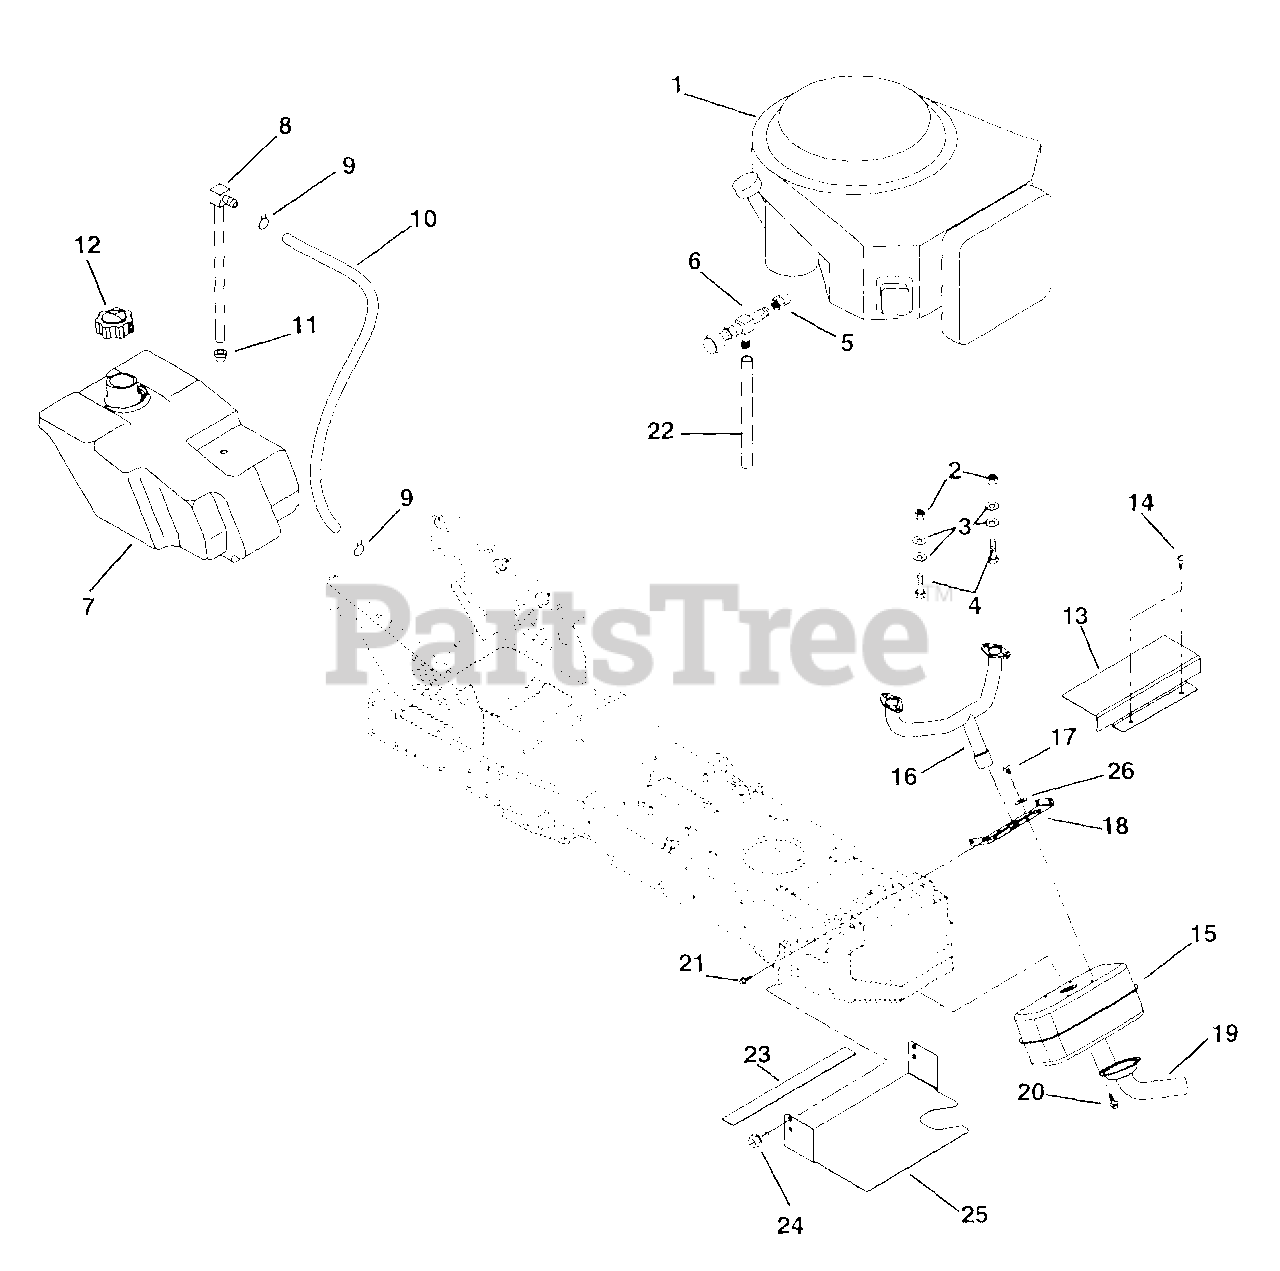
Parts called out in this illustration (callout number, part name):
1	22 HP Briggs & Stratton Engine
1	18 HP V-Twin Briggs & Stratton Engine
2	Nut-Locking-Center .31-18
3	Washer-Flat-Steel .328 x .875 x .062
4	Bolt-Hex .31-18 x 1.50 Grade 5
5	Adapter-Oil Drain
6	Cock-Oil Drain
7	Fuel Tank
8	Tank Fitting
9	Hose Clamp
10	Hose-Fuel Line 48.00"
11	Bushing
12	Fuel Cap
13	Shield-Heat
14	Screw-Tapping .312-18 x .50
15	Muffler-Exhaust
16	Pipe-Exhaust Intek Twin Briggs & Stratton
16	Pipe-Exhaust Vanguard Twin
17	Screw-Tapping 12-24 x .75
18	Bracket-Muffler
19	Deflector-Exhaust
20	Screw-Tapping-Slotted-Hex 8-32 x .38
21	Screw-Tapping-Hex .312-18 x .50
22	Tube Oil Drain
23	Heat Shield Fabric 1 x 10.75
24	Screw-Tapping-Hex Washer Head 12-24 x .75
25	Shield-Heat
26	Washer-Flat .25 x.562 x .049
